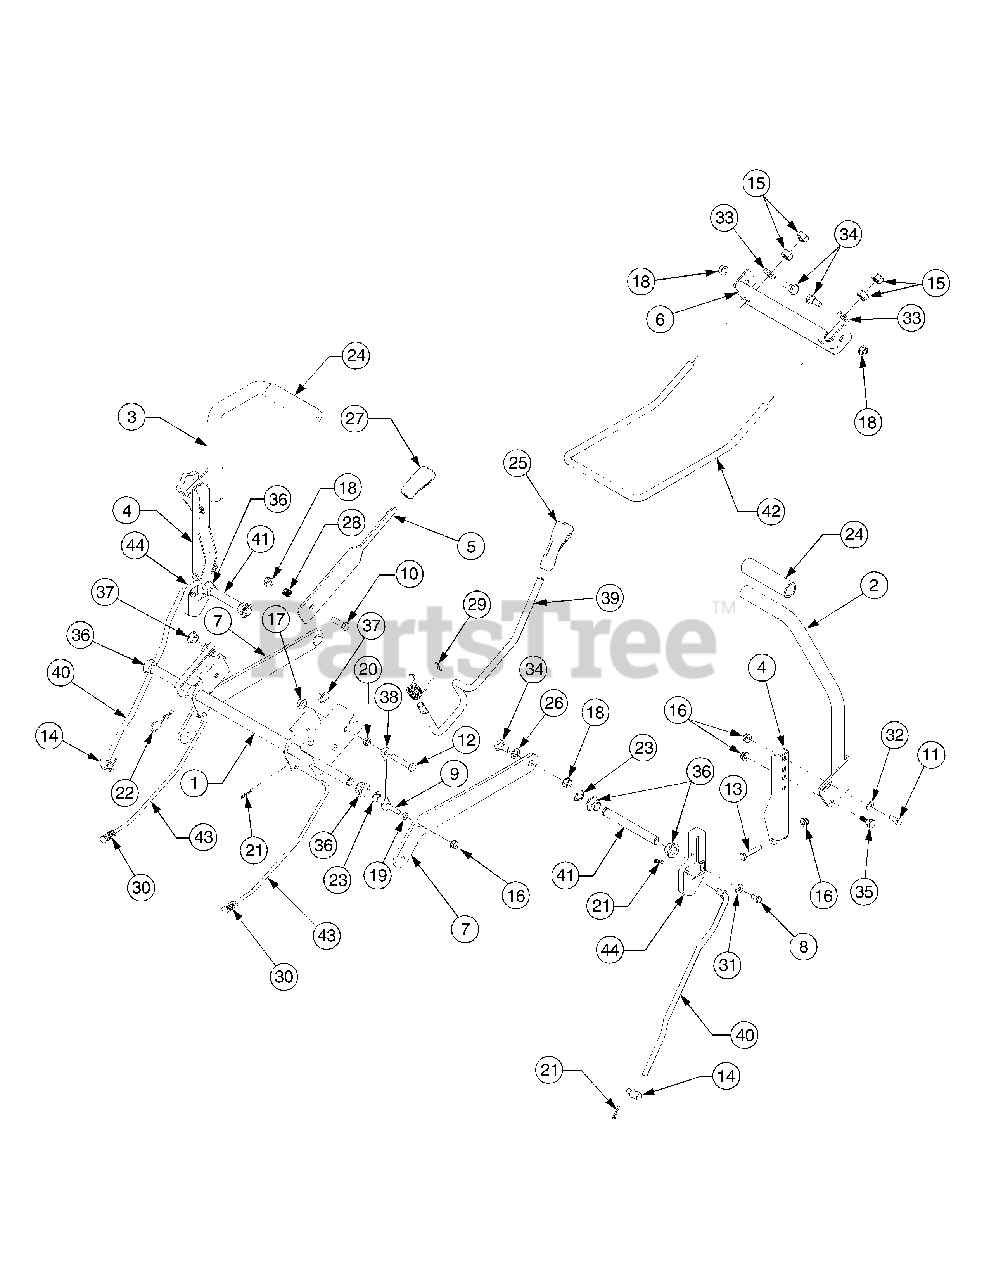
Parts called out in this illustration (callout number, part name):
1	Shaft Assembly, Deck Lift
4	Bracket, Lapbar Pivot
8	Screw, Hex Lock, 1/4-20 x .62 GR5
9	Screw, Hex Cap, 5/16-18 x 1.5 GR5
10	Screw, Hex Cap, 3/8-16 x 1.25 GR5
11	Screw, Hex Cap, 5/16-18 x .75 GR5
12	Screw, Hex Cap, 3/8-16 x 2.0 GR5
13	Screw, Hex Cap, 5/16-18 x 1.75 GR5
14	Ferrule, 3/8-24 x .375
15	Nut, Hex, 1/2-13 GR5
16	Nut, Hx Flange Insert Lck, 5/16-18 GrF
17	Nut, Hx Flange Insert Lck, 3/8-16GrF
18	Nut, Hex Flange Lock, 3/8-16 GRF
19	Nut, Hex Jam, 5/16-18 GR5
20	Nut, Hex Jam, 3/8-16 GR5
21	Pin, Internal Cotter
22	Pin, Internal Cotter
23	E-Ring , .625 Dia. Shaft
24	Grip, Hand
25	Grip, Handle
26	Washer, Flat, .51 x 1.0 x .06
27	Grip, Handle
28	Spring, Compression
29	Spring, Torsion RZT
30	Spring, Compression
31	Washer, Bell, .265 x .75 x .062
32	Washer, Flat, .344 x .688 x .065
33	Washer, Flat, .531 x 1.062 x .134 HT
34	Screw, Shoulder, .498 x .340:3/8-16
35	Screw, Shoulder, .437 x .268:5/16-18
36	Bearing, Hex Flange
37	Bearing, Flange, .626 x .938 x .344
38	Cable, Deck Lift, 5.05 Long
39	Rod, Deck Lift Handle
40	Rod, Lapbar Control
41	Shaft, Control
42	Rod, Deck Front Hanger
43	Rod w/spring, Brake
44	Hub, Control
